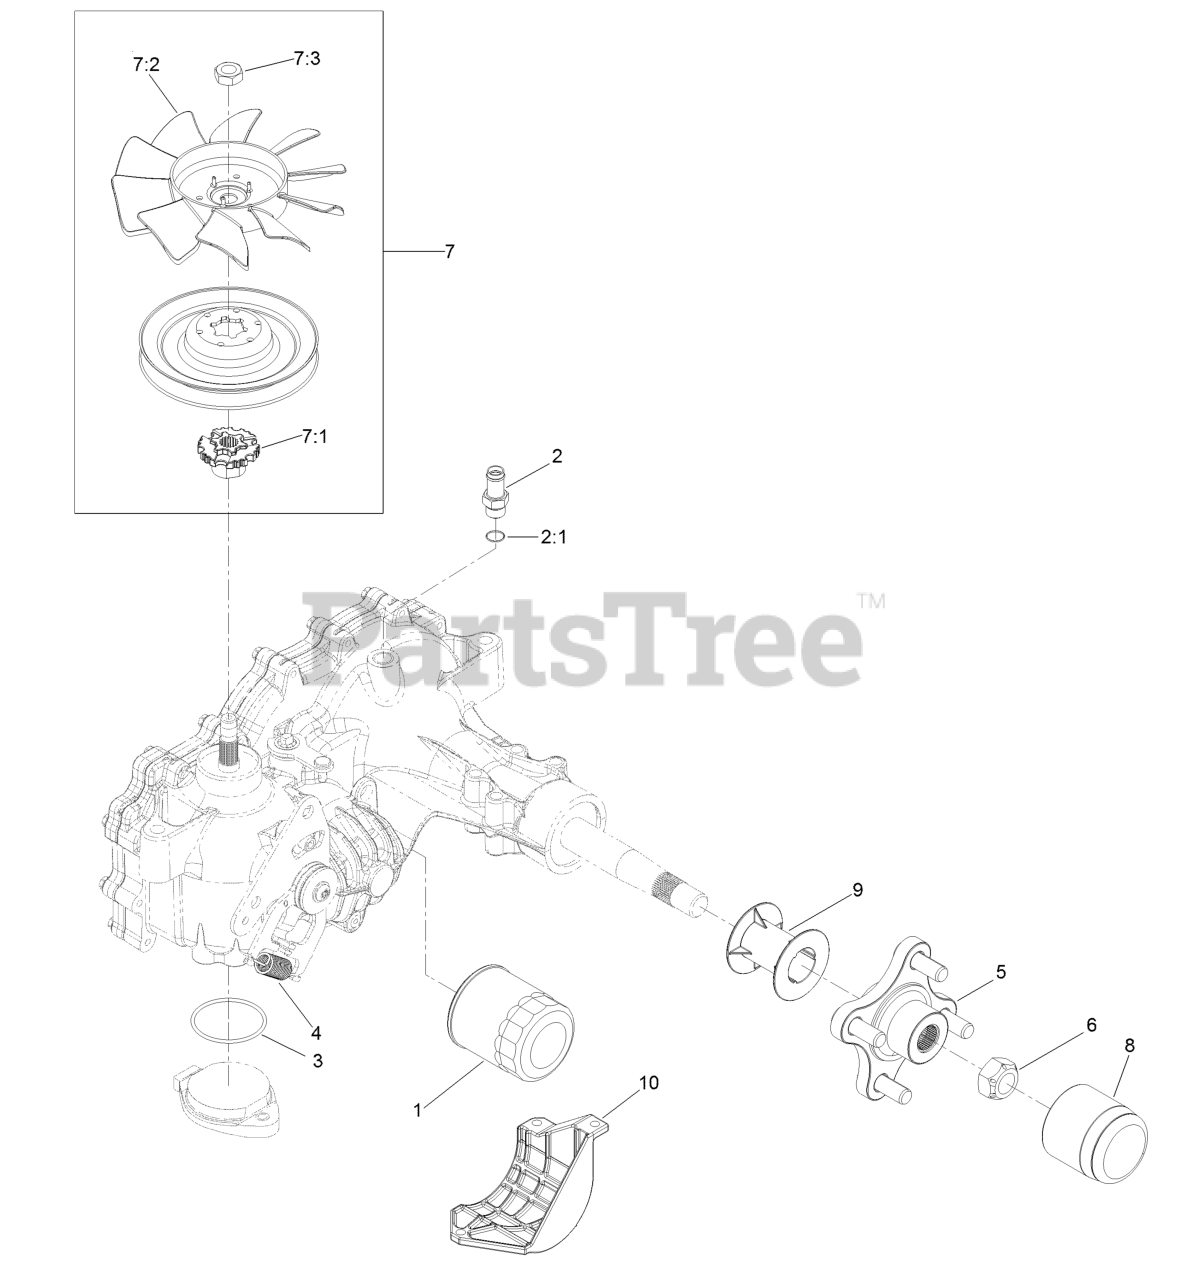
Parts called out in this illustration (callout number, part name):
1	Element-Oil Filter, HYD
2	Adapter-Straight
2:1	O-Ring
3	O Ring-Seal
4	Spring-Extension
5	Hub-Offset
6	Nut-Hub
7	Fan And Pulley Kit
7:1	Hub-Fan
8	Cap-Axle, Long
9	Tube-Axle
10	Guard-Filter, LH
99	Brake Shaft Seal Kit
99	Seal Kit
